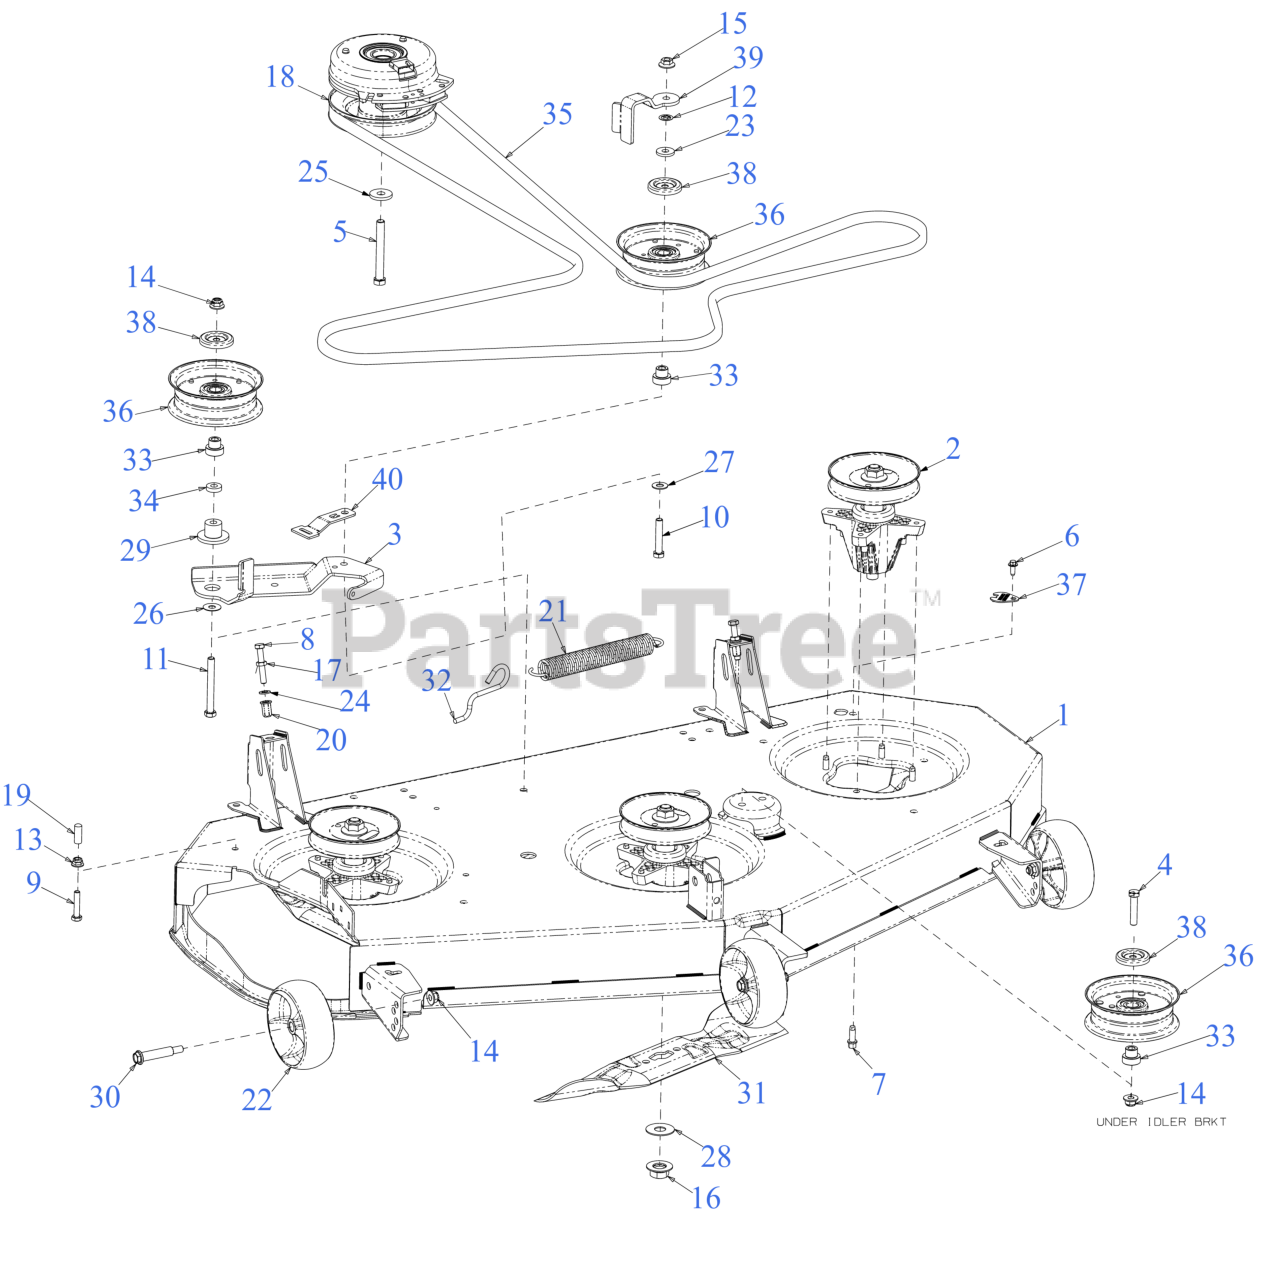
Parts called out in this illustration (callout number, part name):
1	50" FAB DECK SHELL
2	SPINDLE ASSEMBLY (5.37 DIA)
3	DECK IDLER BRACKET
4	HEX SCREW 3/8-16 x 1.75 GR5
5	SCREW 7/16-20 x 3.5 GR5
6	SCREW M6-1 x .625
7	SCREW 5/16-18 x .875
8	SCREW-FULL THREAD 5/16-18 GR5
9	SCREW 5/16-18 x 1.5 LG
10	SCREW 3/8-16 x 2.0 GR 8
11	SCREW 3/8-16 x 3.25 GR8
13	FLANGE LOCK NUT 5/16-18
14	NUT
15	FLANGE LOCK NUT
16	HEX FLANGE NUT 5/8-18 GR5
17	HEX NUT
18	ELECTRIC PTO CLUTCH
20	NUT RIVET 5/16-18
21	EXTENSION SPRING
22	DECK WHEEL (5.0 DIA x 1.875)
23	FLAT WASHER .385 x 1.00 x .135
24	FLAT WASHER
25	FLAT WASHER .445 x 1.248 x .170
26	FLAT WASHER
27	FLAT WASHER .401X.88
28	FLAT WASHER .635X1.585X.062 HDN
29	SHOULDER SPACER
30	SHOULDER BOLT (.50 X 2.0 x 3/8 -16)
31	17.271" BLADE (2IN1) (S SHAPE CENTER HOLE)
31	Cub Cadet 50" HI LIFT BLADE SET (S SHAPE CENTER HOLE) (-05094)
31	Troy-Bilt 50" HI LIFT BLADE SET (S SHAPE CENTER HOLE)
31	17.271" XTREME BLADE (2IN1) (S SHAPE CENTER HOLE)
31	Cub Cadet 50" XTREME BLADE SET (S SHAPE CENTER HOLE) (-05094-X)
31	Troy-Bilt 50" XTREME BLADE SET (S SHAPE CENTER HOLE)
31	17.271" LOW LIFT (S SHAPE CENTER HOLE)
31	Cub Cadet 50" LOW LIFT BLADE SET (S SHAPE CENTER HOLE) (-05094-X)
31	Troy-Bilt 50" LOW LIFT BLADE SET (S SHAPE CENTER HOLE)
32	DECK SPRING HOOK
33	SHOULDER SPACER
35	V-BELT B SEC x 143.5 LG
35	Cub Cadet 50" DECK DRIVE BELT
35	Genuine Factory Parts 50" DECK BELT
36	IDLER PULLEY 4.50" DIA
37	DECK WASH PLUG
38	IDLER PULLEY CAP
39	BELT KEEPER
